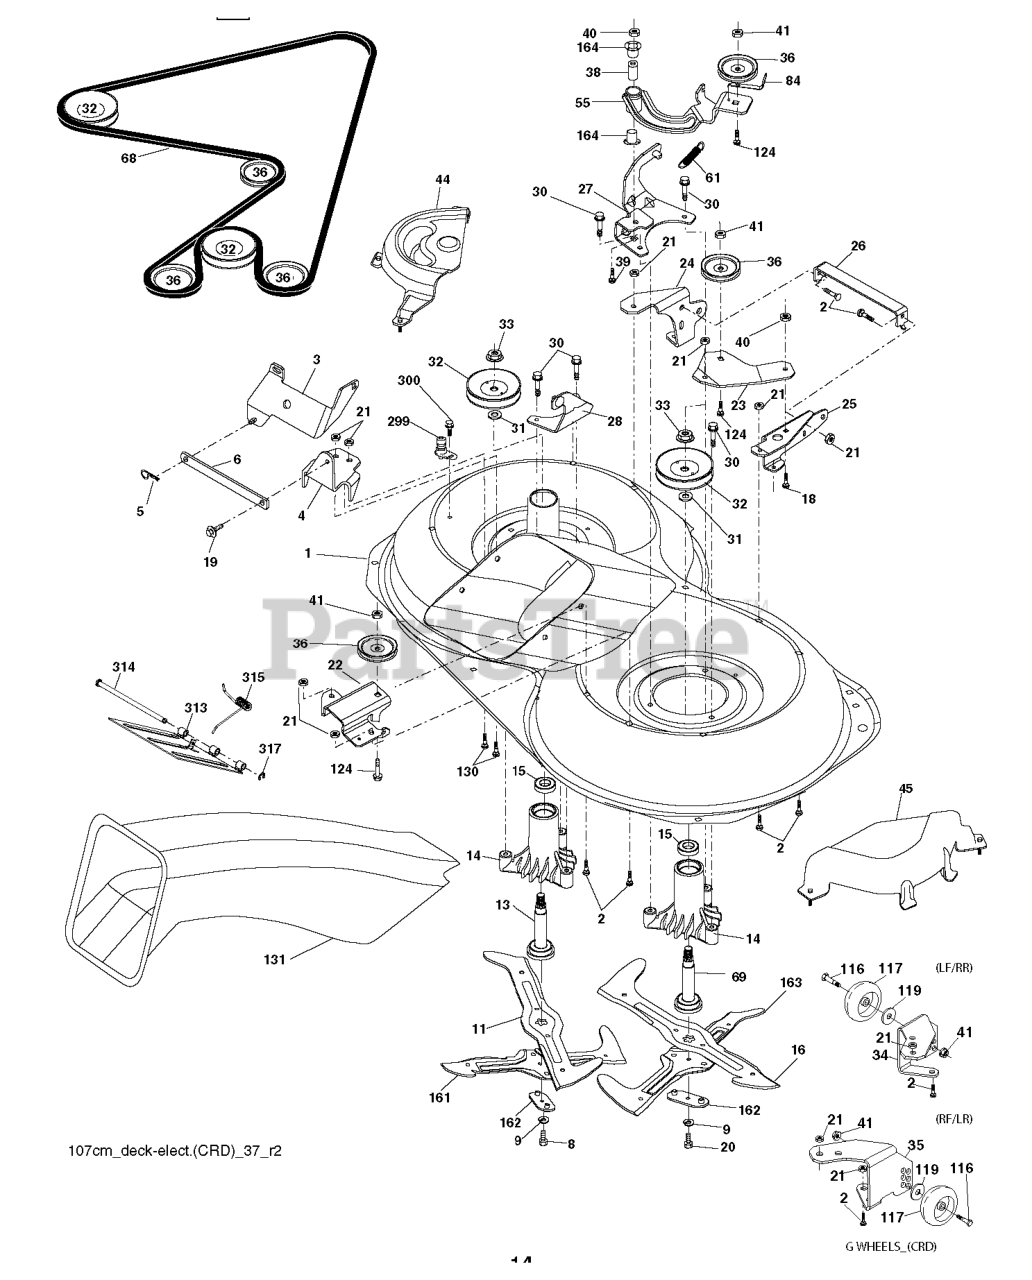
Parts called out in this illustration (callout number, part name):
2	RP BOLT 5/16-18 X3/4 ZN/YEL GR
3	BRACKET.ASM.BAR.SWAY.CHASS
5	RETAINER-SPRNG RB
6	BAR.SWAY.92.CRD
8	BOLT.3/8-24X1.25 GR8
9	LOCKWASHER
11	BLADE.3N1.LH.CRD
13	SHAFT ASM VENT
14	HOUSING.MANDREL.VENTED (MACHD)
16	BLADE.3N1.RH.CRD
19	BOLT SHD 5/16-18
20	BOLT.3/8-24X1.25GR8. LHTHRD
21	LOCKNUT
22	BRACKET.IDLER.RR.107.CRD
24	BRACKET
25	BRACKET RF
26	SUPPORT
28	BRACKET
30	SCREW, WASHER HEAD
31	WASHER.SPACER.MANDREL
32	PULLEY.MANDREL.4.80 PD.2006
33	NUT.FLANGE.LOCK.TOP
34	BRACKET
35	BRACKET
36	PULLEY.IDLER.4.25
41	NUT LOCK FLG 3/8-16 UNC
55	ARM.IDLER.107.CRD
61	SPRING
68	HEX-BELT 107 MOWER
69	SHAFT.ASM.W/LWR.BRG.RH.THREAD
84	KEEPER, BELT IDLER
116	BOLT.SHOULDER.3/8-16X3-5/8.
117	RP WHEEL. GUAGE RALLY
119	WASHER
124	BOLT.3/8-16X1.50
130	BOLT.CARR.SQNK.5/16-18UNC.X3/4
161	BLADE 107CM.CROSS.BLADE
162	ADAPTER ADAPTER.CROSSBLADE.107
163	BLADE.CROSS.RH.CRD.107
164	BRNG T
299	PORT.WASHOUT
300	SCREW.TT.#10-32X.5.3/8.FLANGE
313	COVER DOOR.107 CM CRD EZ MULCH
314	PIN PIN.HINGE
317	E-RING.5/16"
